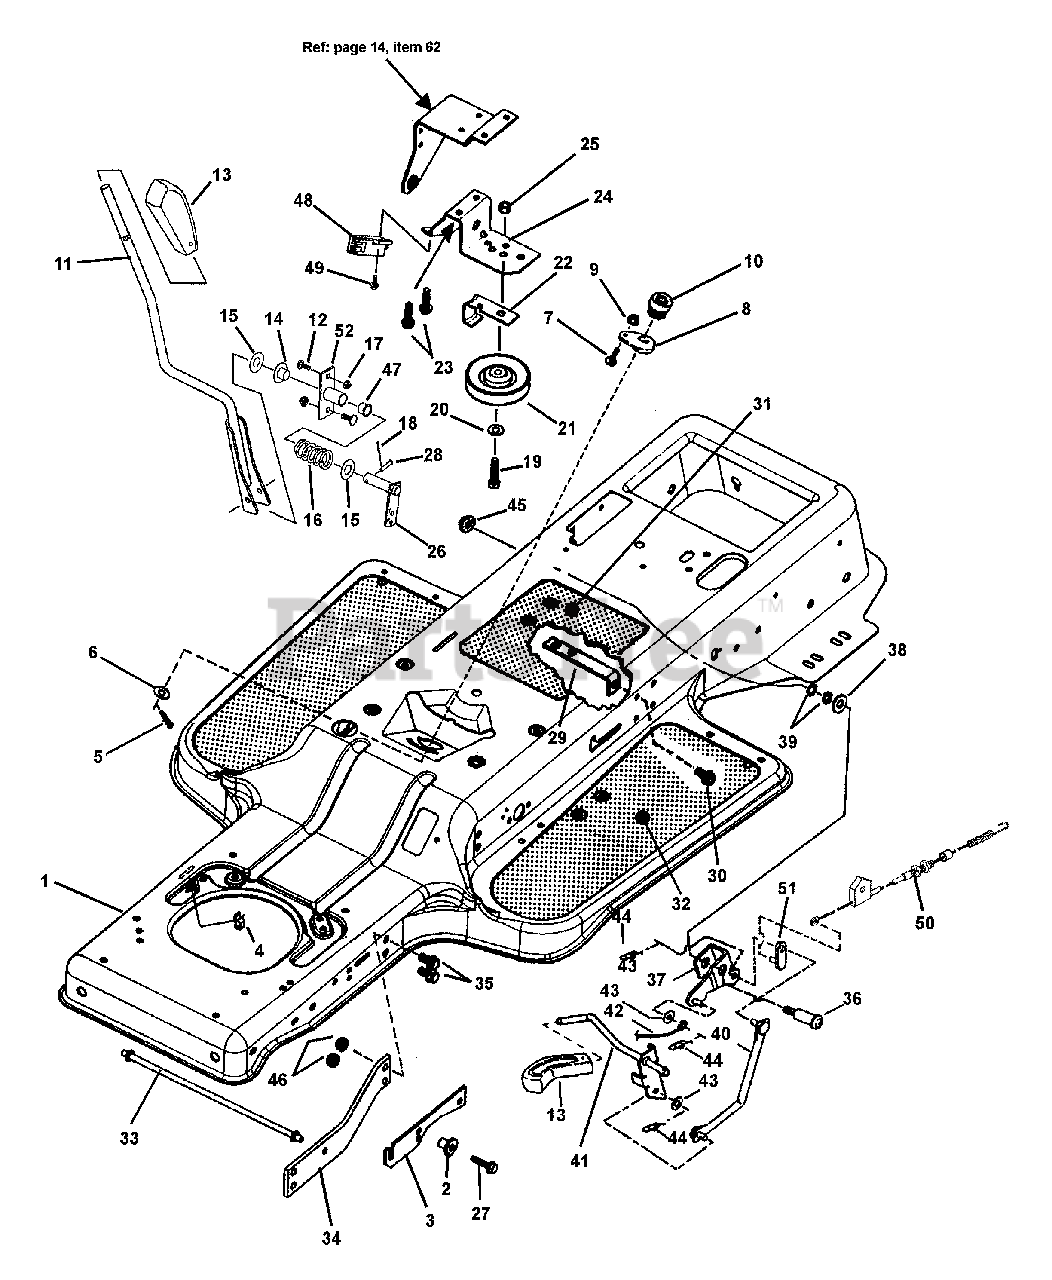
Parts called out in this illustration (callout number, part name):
1	FRAME, Tractor (1 Piece)
2	BUSHING, Flange
3	BRACKET, Hood Pivot
4	CLIP, Wire
5	PIN, 1/8 x 3/4" Cotter
6	WASHER, 1/2 Shim
7	BOLT, 1/4-20 x 5/8" Short Neck Carriage, Grade 5
8	ASSEMBLY, Steering Adjuster
9	NUT, 1/4-20 Hex Flange Lock, Grade 5
10	GEAR, Steering Pinion
11	LEVER, Shift (Upper)
12	BOLT, 5/16-18 x 3/4" Carriage
13	KNOB, Deck Lift Lever
14	BUSHING, 314 Flange
15	WASHER, Thrust
16	SPRING, Shift Detent
17	NUT, 5/16-18 Flange Lock
18	PIN, 3/32 x 3/4" Cotter
19	SCREW, 3/8-16 x 1-1/2" Hex Head Cap, Grade 5
20	WASHER, 3/8" Flat
21	PULLEY, Idler
22	GUIDE, Pulley Belt
23	SCREW, 5/16-18 x 1-1/4" Swage
24	SUPPORT, PTO Lever
25	NUT, 3/8-16 Hex Center Lock, Grade 5
26	STRUCTURE, Arm
27	SCREW, 5/16-18 x 1-1/4" Self-Tapping
28	PIN, 1/4 x 1-5/8" Clevis
29	ANCHOR, Blade Brake
30	SCREW, 3/8-16 x 5/8" Hex Washer Self-Tap
31	DECAL, Instruction Frame Top
31	DECAL, Instruction Frame Top (Euro)
32	PAD, Foot (Rubber Deluxe)
33	GUIDE, Belt
34	BRACE, Frame
35	BOLT, 3/8-16 x 3/4" Hex Flange Lock
36	BOLT, 1/2-13 Shoulder
37	WELDMENT, Bellcrank PTO
38	WASHER, Thrust
39	WASHER, 1/2" Internal Tooth Lock
40	WELDMENT, PTO Link
41	WELDMENT, PTO Lever
42	CABLE, 33 Blade (33" Deck)
42	CABLE, PTO (38" Deck)
43	WASHER, 7/16" Flat
44	COTTER PIN, 3/8 Self-Lock
45	NUT, 1/2-13 Hex Flange Lock, Grade 5
46	NUT, 3/8-16 Hex Flange Lock
47	BUSHING, 3/4 Flange
48	SWITCH, DPDT NC/NO
49	SCREW, #10-32 x 5/8" Self-Tap.
50	ASSEMBLY, Cable
51	WELDMENT, Bracket
52	WELDMENT, Pivot Plate
